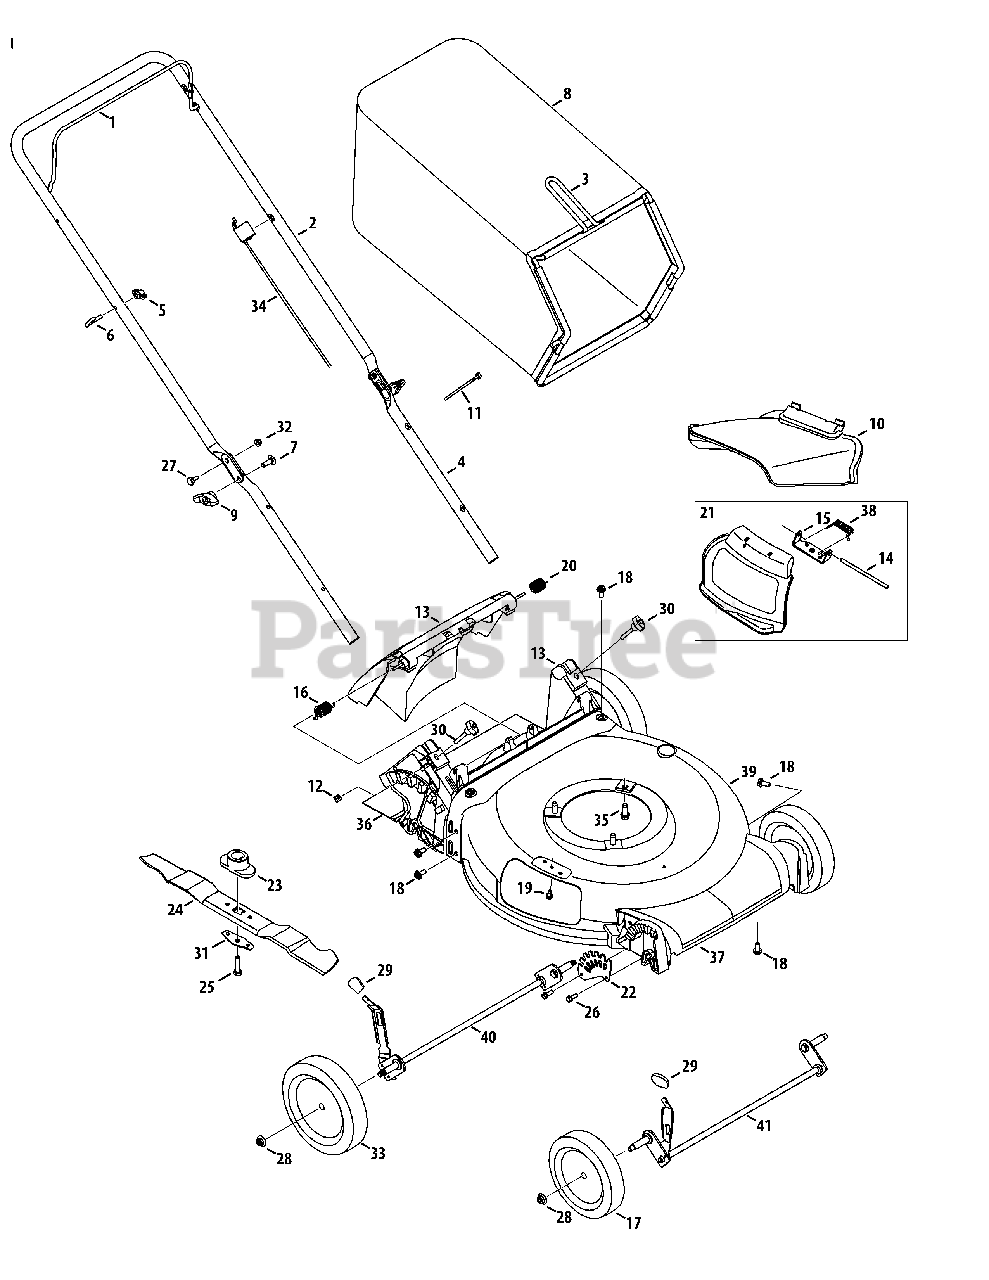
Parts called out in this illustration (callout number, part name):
1	Blade Control
2	Upper Handle, Non-Adjustable
3	Grass Catcher Frame
4	Lower Handle
5	Wing Nut
6	Rope Guide
7	Carriage Screw ,5/16-18
8	Grass Bag
9	Wing Knob, Red
10	Side Chute
11	Cable Tie
12	Nut, Sq., 1/4-20
13	Rear Discharge Door Assembly
14	Hinge Pin
15	Chute Deflector Bracket
16	Torsion Spring - RH
17	Front Wheel Gray
18	Screw, 5/16-14 x .750
19	Screw, 1/4-20 x .500
20	Torsion Spring - LH
21	Hinged Mulch Plug Assembly
22	Front Height Adjuster Plate
23	Blade Adapter
24	Mulching Blade
25	Screw , 3/8-24 x 1.50
26	Screw, 1/4-15 x .750
27	Sldr. Screw, .375 x .126 x 1/4-20
28	Flange Lock Nut, 3/8-16
29	Adjustment Lever Knob, Red
30	Wing Nut
31	Blade Bell Support
32	Nut, Flange Lock, 1/4-20
33	Rear Wheel Gray
34	Control Cable, 37.58"
35	TT Sems Screw, 3/8-16 x 1.0
36	Trail shield
37	Front Cover
38	Torsion Spring
39	Deck , 21" - Universal Red
40	Rear Axle Assembly
41	Front Axle Assembly
